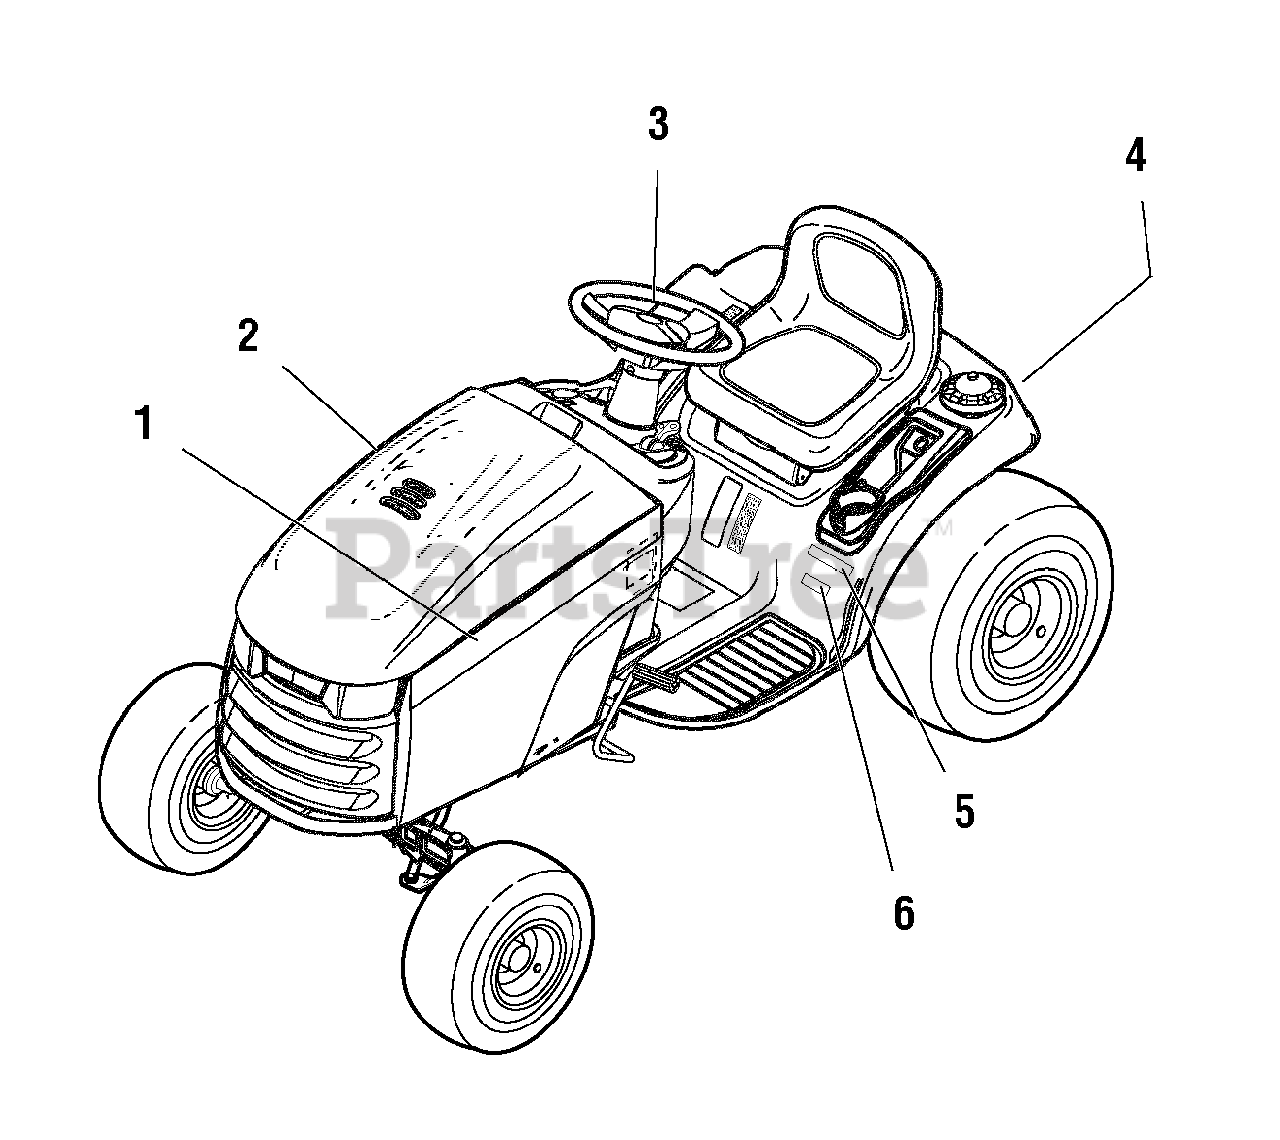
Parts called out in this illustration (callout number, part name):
1	DECAL, Simplicity, LH Stripe
2	DECAL, Simplicity, RH Stripe
3	DECAL, SMI Steering Wheel Icon Orange
4	DECAL, Simplicity
5	DECAL, Regent, Silver & Blue, 1 x 3-11/16
5	DECAL, Regent EX, Silver & Blue, 1 x 5-5/16
5	DECAL, ELT2246, Silver/Clear
5	DECAL, Model, ELT2046
6	DECAL, 18.5HP, Silver/Clear
6	DECAL, 19.5HP, Silver/Clear
6	DECAL, 22HP, Silver/Clear
